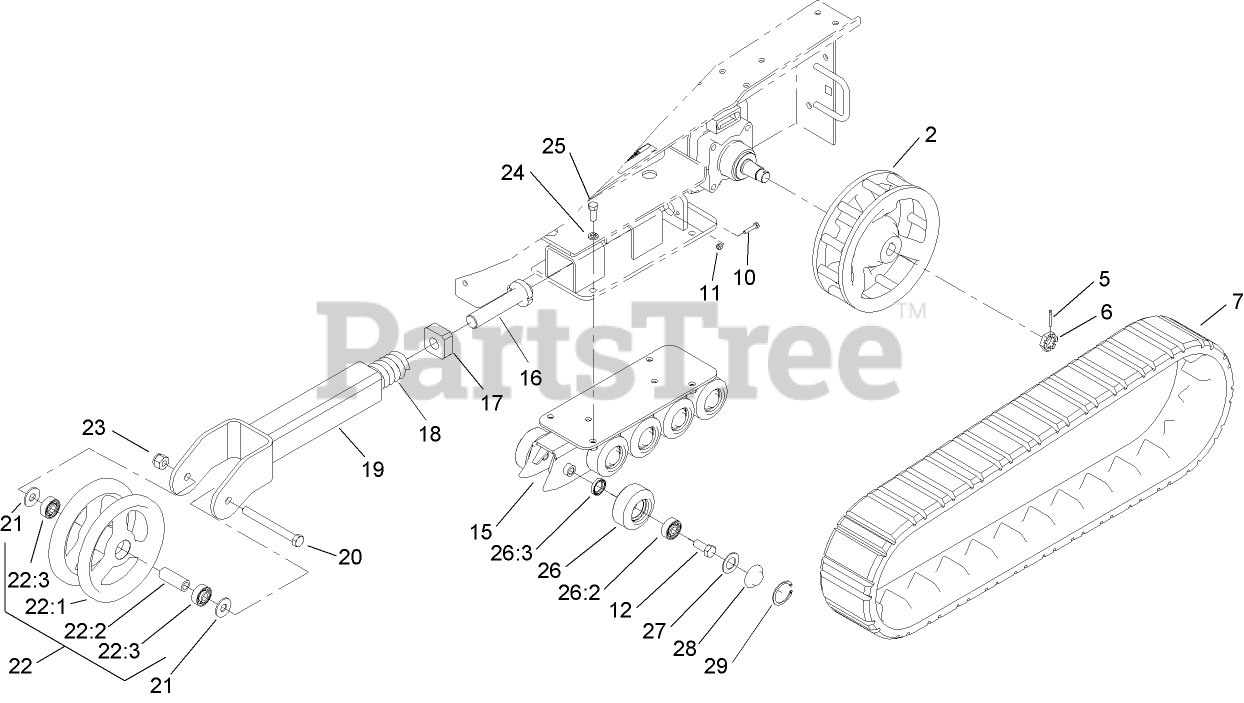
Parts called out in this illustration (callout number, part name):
2	WHEEL-DRIVE, TX 420
5	PIN-COTTER
7	TRACK
10	SCREW-HH
11	NUT-LOCK, NI
12	SCREW-HH
15	TRACK GUIDE ASM
16	BOLT-TENSIONER
17	BLOCK-TENSIONER
18	SPRING-COMPRESSION
19	TENSIONER ARM ASM
20	SCREW-HH
21	WASHER-FLAT
22	TENSIONER WHEEL ASM
22:1	WHEEL-TENSIONER
22:2	SPACER-WHEEL, TENSIONER
22:3	BEARING
23	NUT-HEX
24	WASHER-LOCK
25	SCREW-HH
26	Road Wheel ASM
26:2	BEARING
26:3	SEAL-OIL
27	Gasket-Bogie
28	CAP-WHEEL, BEARING
29	RING-SNAP, INTERNAL
